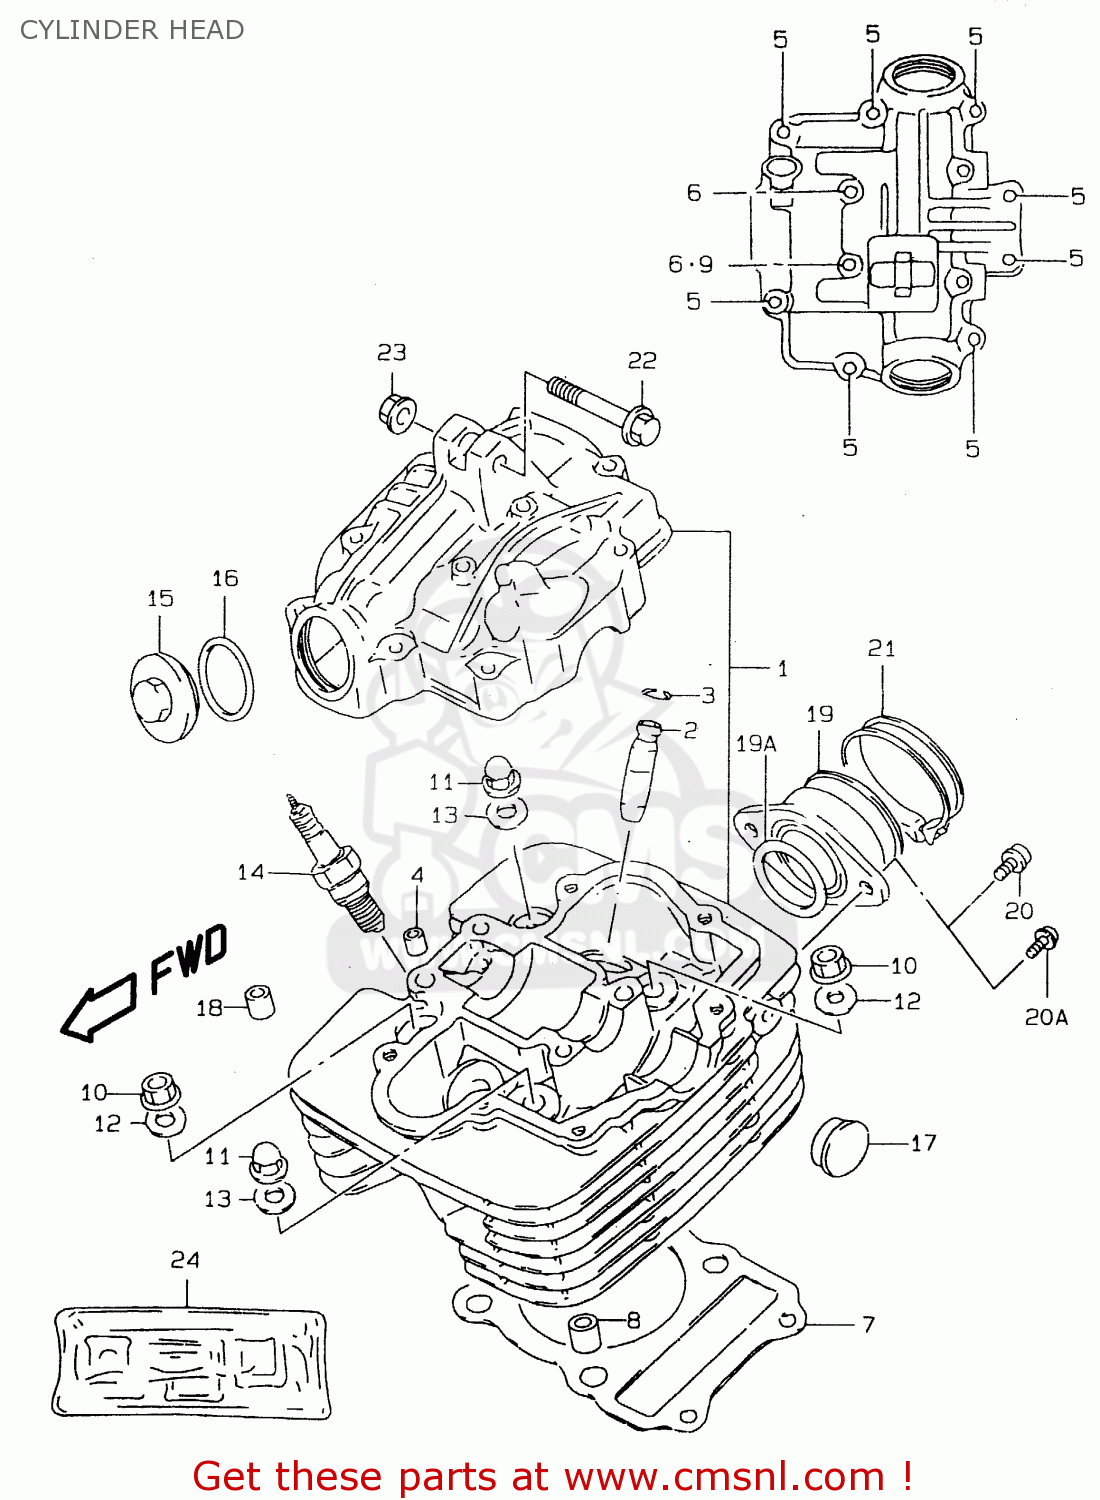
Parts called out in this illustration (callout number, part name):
1	HEAD ASSY,CYLINDER
2	GUIDE,VALVE
3	RING,SNAP
4	PIN(6.2X8X11)
5	BOLT
6	BOLT
7	GASKET,CYLINDER HEAD (NAS)
8	PIN
9	GASKET(5.8X13X1.2) (NAS)
10	NUT
11	NUT
12	WASHER (8.5X19X2.3)
13	GASKET(8.5X17X2.3) (NAS)
14	PLUG,SPARK(DR8EA)
15	CAP,INSPECTION
16	O RING(D:3,ID:29.5)
17	PLUG(OD:22.5)
18	PAD,CYLINDER HEAD
19	PIPE,INTAKE
19A	O RING,INTAKE PIPE
20	SCREW
21	CLAMP
22	BOLT 8X50
23	NUT
24	GASKET SET
